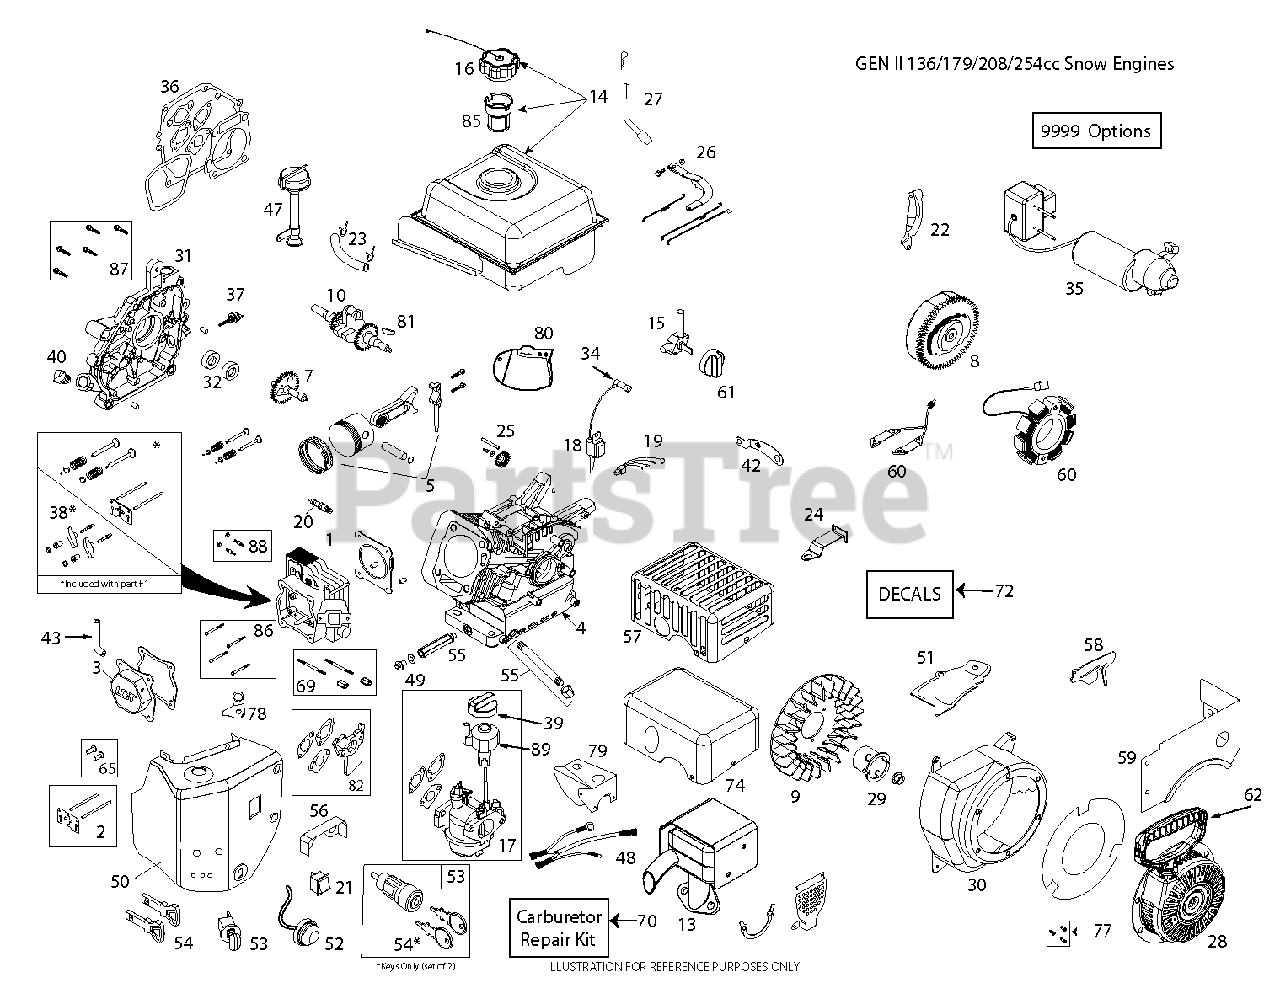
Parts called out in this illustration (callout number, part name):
1	CYLINDER.HEAD.ASM.W/GASKET.254
2	KIT.PUSH.ROD.&.PLATE.W/VC.GASK
3	COVER.VALVE.W/GASKET.254CC
4	CYLINDER LCT 254 FT OIL DRAIN
5	PISTON.&.ROD ASSEM.254CC
7	CAMSHAFT.MCR.W/GASKET.254CC
8	FLYWHEEL.ELEC.STRT.(8.MAGNETS)
9	KIT.COOLNG.FAN.SERV(SK208-4000
10	CRANKSHAFT KEYED #18 LCT 254
13	MUFFLER.ASSEM.GEN2.SNOW.254CC
14	FUEL TANK LCT 254 2.7L GLOSS
15	FUEL.PETCOCK.SNOW(SKSN4900)
16	FUEL CAP OVERSIZED CLICK STYLE
17	CARBURETTOR LCT 254 W/IDLEDOWN
18	COIL.ING.CDI.HI TEMP.SKSNO416.
20	PLUG.SPARK.PLAT.SKSN2404.1
21	SWITCH.ON/OFF(SKSN-0403)
22	SHIELD.FLYWHEEL.ELEC.STRT.208C
23	FUEL HOSE KIT
24	BRACKET.SPEED.CNTRL.FIXED.254C
25	GOVENOR.GEARS ASM(SK2082900)
26	KIT.GOVERNOR.ARM.&.LINK.254CC
27	KIT.GOVERNOR.CRANK(SK208-3100)
28	RECOIL.STRT.ROUND(BLK) SNOW
29	STRTER.CUP(NON-SLOT)SKSN0601.2
30	BLOWER HSG.LCT 254 GLOSS BLK S
31	CRANKCASE.CVR.PRESS.IN.HI-OIL.
32	KIT.SEAL.OIL.2.PIECES.254CC
34	SPARK.PLUG.BOOT.SNW,SKSN4691.1
35	STARTER.EL.230C.SNO.LCT.208CC.
36	KIT.ENGINE.GASKET.254CC
38	KIT.ROCKER.ARM.W/GASKET.254CC
39	CHOKE.KNOW.SNOW(SKSN4500)
40	NON REMOVABLE PLUG
43	TUBE.BREATHER.LCT.208
47	TUBE ASSY HIGH OIL-FILL
48	WIRE.HARNESS.SNOW
49	KIT.OIL.DRAIN.PLUG(SK2089911
50	BOX HEATER ASM.LCT 254
52	PRIMER.BULB.WITH HOSE (SNOW)
53	SWITH.KEY.ASSEM.SNOW.SINGLE.ST
54	KEY SET(2 KEYS) SKSN0407.1
55	OIL PIPE DRAIN LCT 254
56	SHIELD.CARBURETOR.VAPOR
57	SHIELD.MUFFLER.CE.COMPLIANT
58	SHIELD.GOVERNOR.LINKAGE.254CC
59	FUEL TANK SKIRT SHIELD LCT 254
60	208CC 60W ALTERNATOR
61	FUEL KNOB-SNOW
62	HANDLE.RECOIL.DELUXE.LCT
65	TAPPET.KIT.LCT.208CC
69	CARB.STUDS & COUPLING KIT.SNOW
70	CARB.REPAIR.KIT.LCT.SK9900.2
74	COVER.MUFFLER.HEAT.SHIELD.
77	BOLT.KIT.RECOIL.LCT.ALL.ENGINE
79	COVER.CARBURETOR.SNOW
80	SHIELD.GOVERNOR.LINK.SNOW.254C
81	Husqvarna TBD
82	SPACER.CARBURETOR.208CC.LCT
85	DECAL.HOOD.RH.
86	KIT.BOLT.CYLINDER.HEAD.(4PC)
87	KIT.BOLT.CRANKCASE.COVER.6PC
88	STUD.MUFFLER.KIT.LCT
89	KNOB LCT.SKSN5325.1 SPEED
9999	JET HIGH ALTITUDE LCT 5000 25
